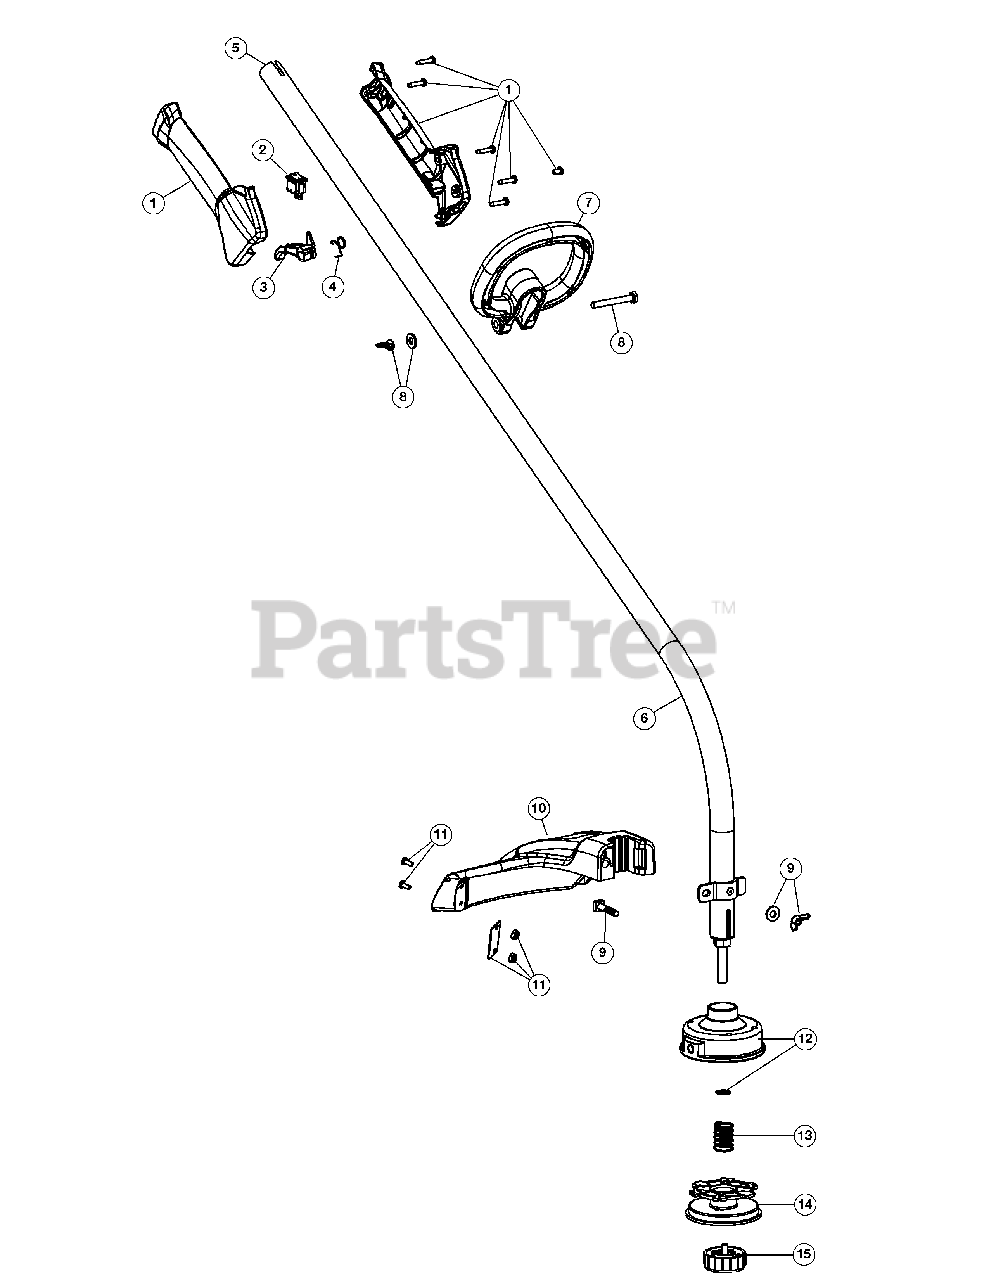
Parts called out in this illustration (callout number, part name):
1	Throttle Housing Assembly (Incl. 2-4)
3	Throttle Trigger
4	Throttle Trigger Spring
5	Flexible Drive Shaft
6	Drive Shaft Housing Assembly (Incl. 5)
7	D-Handle (Incl. 8)
8	D-Handle Hardware Assembly
9	Shield Mounting Hardware
10	Shield Assembly (Incl. 9 & 11)
11	Blade Assembly
12	Outer Spool w/Retainer
14	Inner Reel
15	Bump Head Knob Assembly
